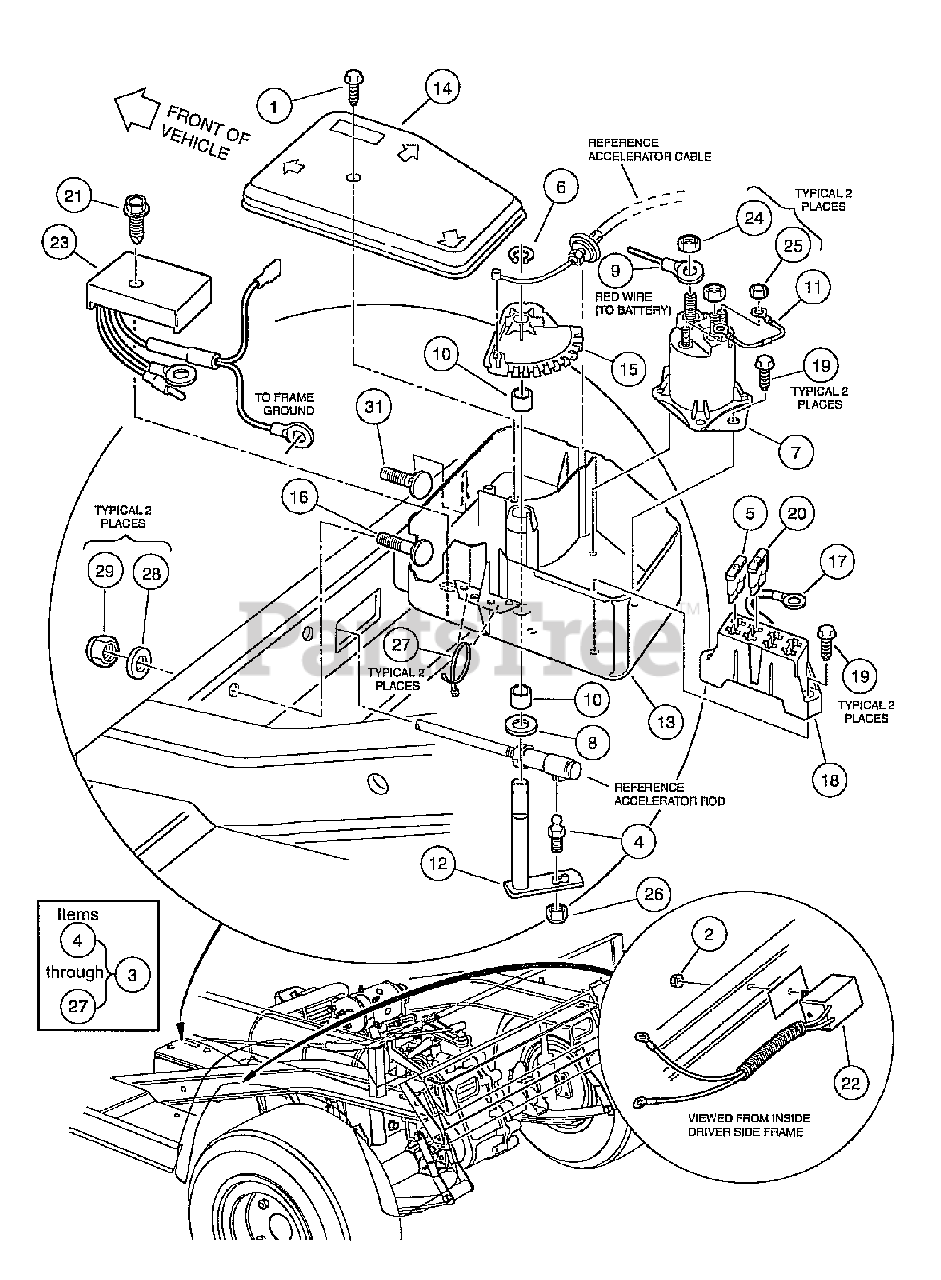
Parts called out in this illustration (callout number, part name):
1	Screw, #12-16 X 0.625 Hi-Lo
2	Locknut, 5/16-18 Hex Flange
3	Assembly, Electrical Component Box
4	Stud, 1/4-28 X 0.560 Ball
5	Fuse, 10-Amp
6	Ring, 0.338" Internal Retaining
7	Solenoid, 12-Volt
8	Washer, 0.38" Id Delrin Flat
9	Wire Assembly #6 Red
10	Bushing, Secondary Weight, Split
11	Assembly, Diode
12	Bell Crank and Shaft Assembly
13	Box, Electrical Component
14	Cover, Electric Box
15	Cam, Electric Box
16	Bolt, Carriage, 5/16-18 X 2.0
17	Wire Assy, #10 Red
18	Fuse Block
19	Screw, #12.16 X 0.625 Hi-Lo
20	Fuse, 20-Amp
21	Screw, 1/4-15 X 1.50 Hi-Lo Hex
22	Diode Assembly
23	Voltage Regulator
24	Nut, 5/16-18 Hex
25	Nut, #10-32 Hex
26	Locknut, 1/4-28 Nylon Insert
27	Tie Wrap, 8" Nylon
28	Washer, 5/16 Type A Flat
29	Locknut, 5/16-18 Nylon Insert
30	Bolt, Carriage, 5/16-18 X 1.5
